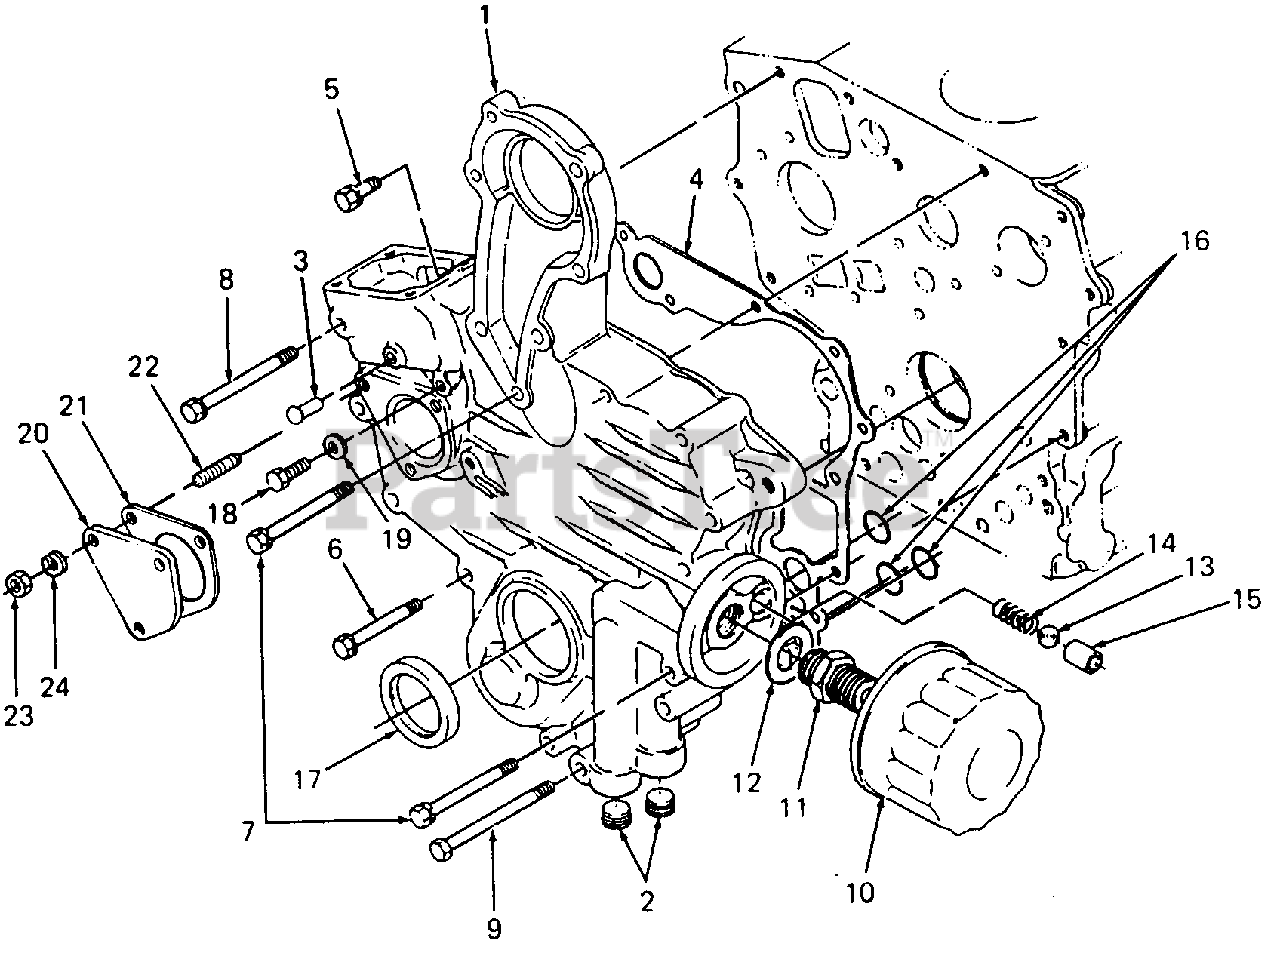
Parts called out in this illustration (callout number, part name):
1	Gear Case Assy
4	Gasket, Gear Case
10	Element, Filter
12	Washer, Plain
24	Washer, Spring
